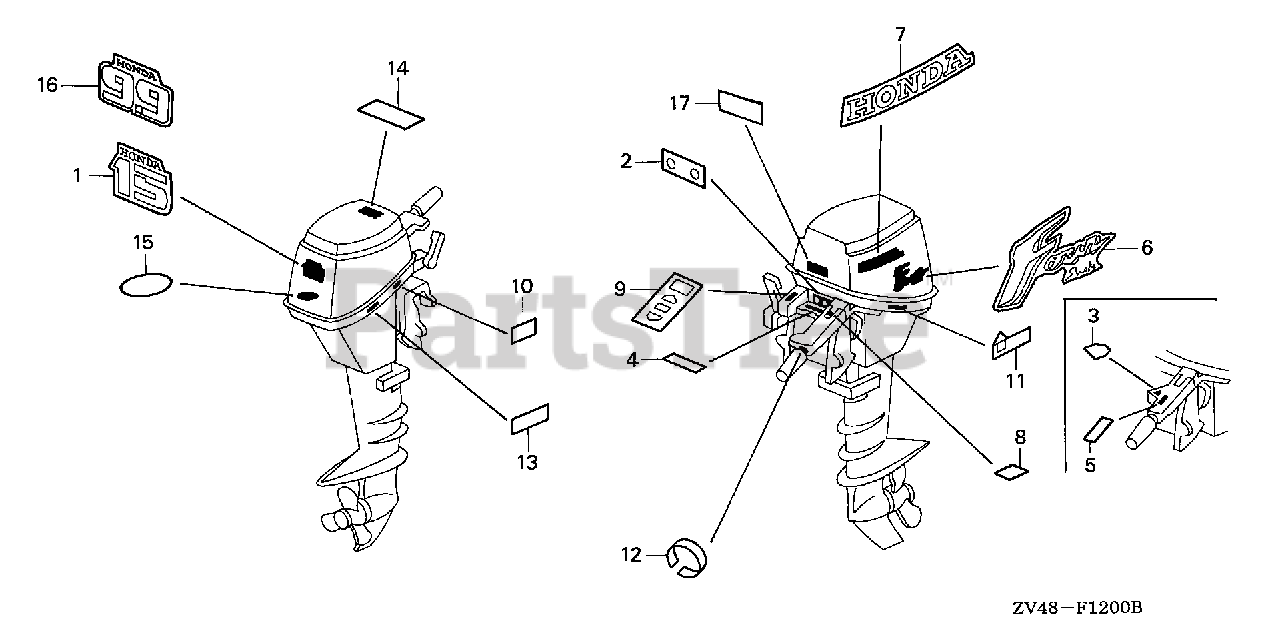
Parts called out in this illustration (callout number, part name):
2	LABEL, INDICATION (E)
3	MARK, EMERGENCY SWITCH INDICATION (ENGLISH)
4	MARK, STARTER (ENGLISH)
5	MARK, SPARE CLIP (ENGLISH)
6	MARK, SIDE EMBLEM
7	MARK, SIDE STRIPE (HONDA)
8	LABEL, SPECIFICATION
9	MARK, CHANGE (ENGLISH)
10	MARK, RECEPTACLE (6A)
11	LABEL, OIL CAUTION (ENGLISH)
12	MARK, THROTTLE (E)
13	LABEL, STORING CAUTION (ENGLISH)
14	LABEL, WARNING OPERATOR (ENGLISH)
15	MARK, ENVIRONMENT (EPA 2006)
16	MARK, RR. (9.9)
